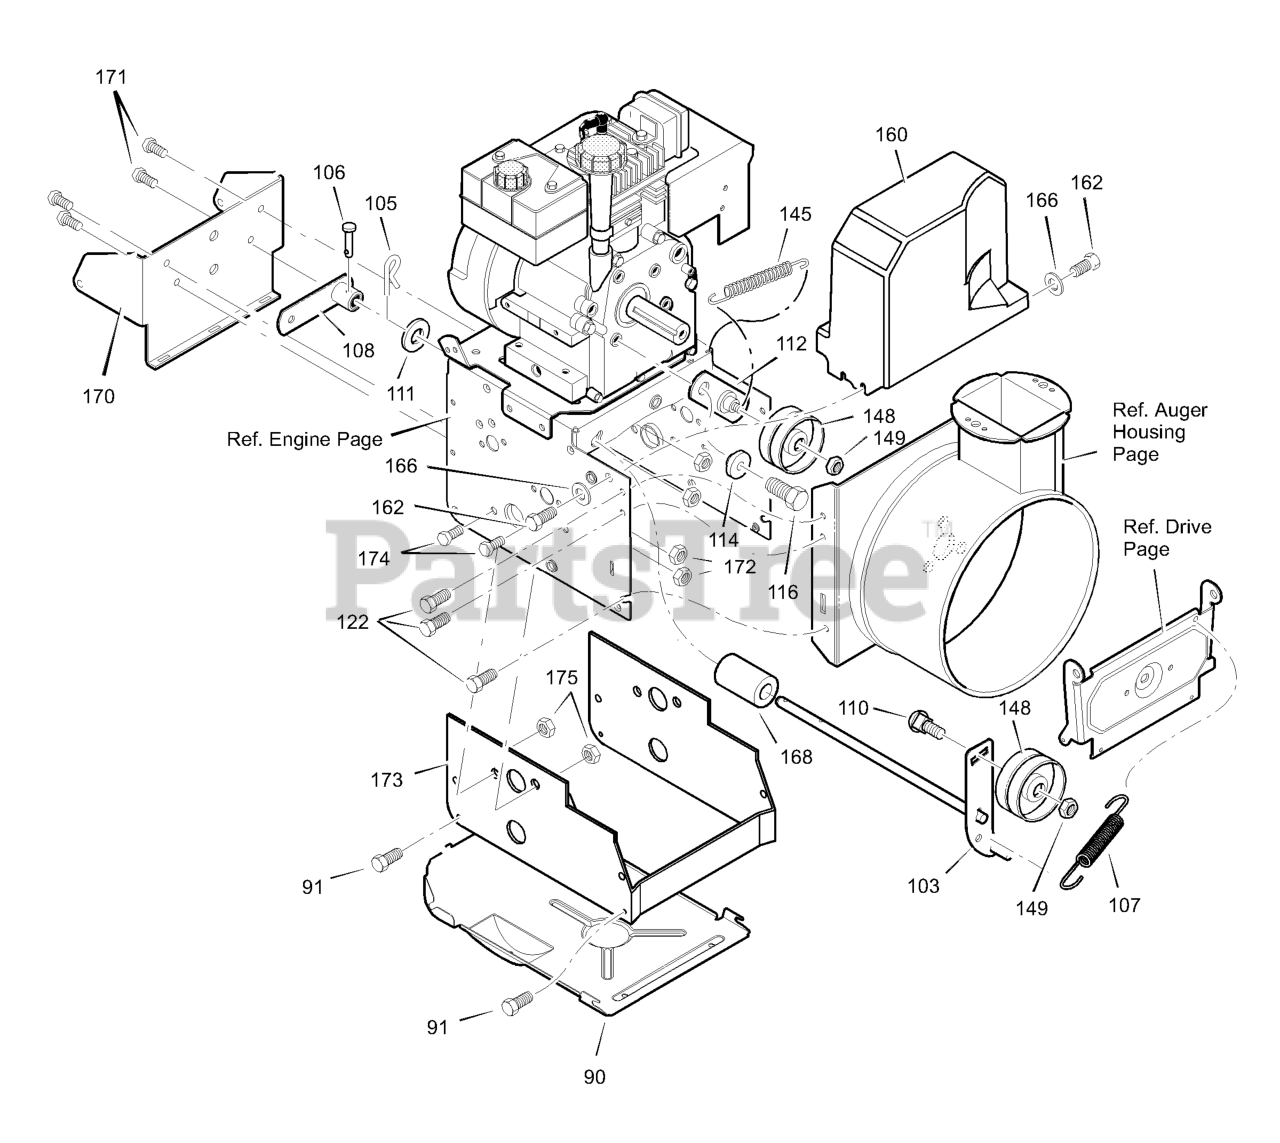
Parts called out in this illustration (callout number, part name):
90	COVER, BOTTOM
91	SCREW, 1/4-20X .63
103	IDLER ASSEMBLY, AUGER
105	PIN, HAIR .38DIAX1.64LG
106	PIN, CLEVIS 3/16" DIA
107	SPRING, TENSION
108	ASSY., SPRING ATTACH
110	BOLT, 3/8-16X1.25 CARR.
111	WASHER, FLAT
112	BRACKET ASSEMBLY, IDLER
114	BUSHING, IDLER BRACKET
116	SCREW 5/16-24 X 1.00
122	SCREW, TAP 5/16-18 X .50
145	SPRING, IDLER TRACTION DRIVE
148	PULLEY, IDLER
149	NUT, JAM 3/8-16
160	COVER, BELT
162	SCREW, TAP 1/4-20 X .63
166	WASHER, FLAT
168	SPACER, AUGER BRACKET
170	BRACKET, TRACK SUPPORT
171	SCREW, 5/16-18 x 0.75
172	NUT, 5/16-18
173	EXTENSION, FRAME
174	SCREW, 3/8-16 X 0.75
175	NUT, 3/8-16
